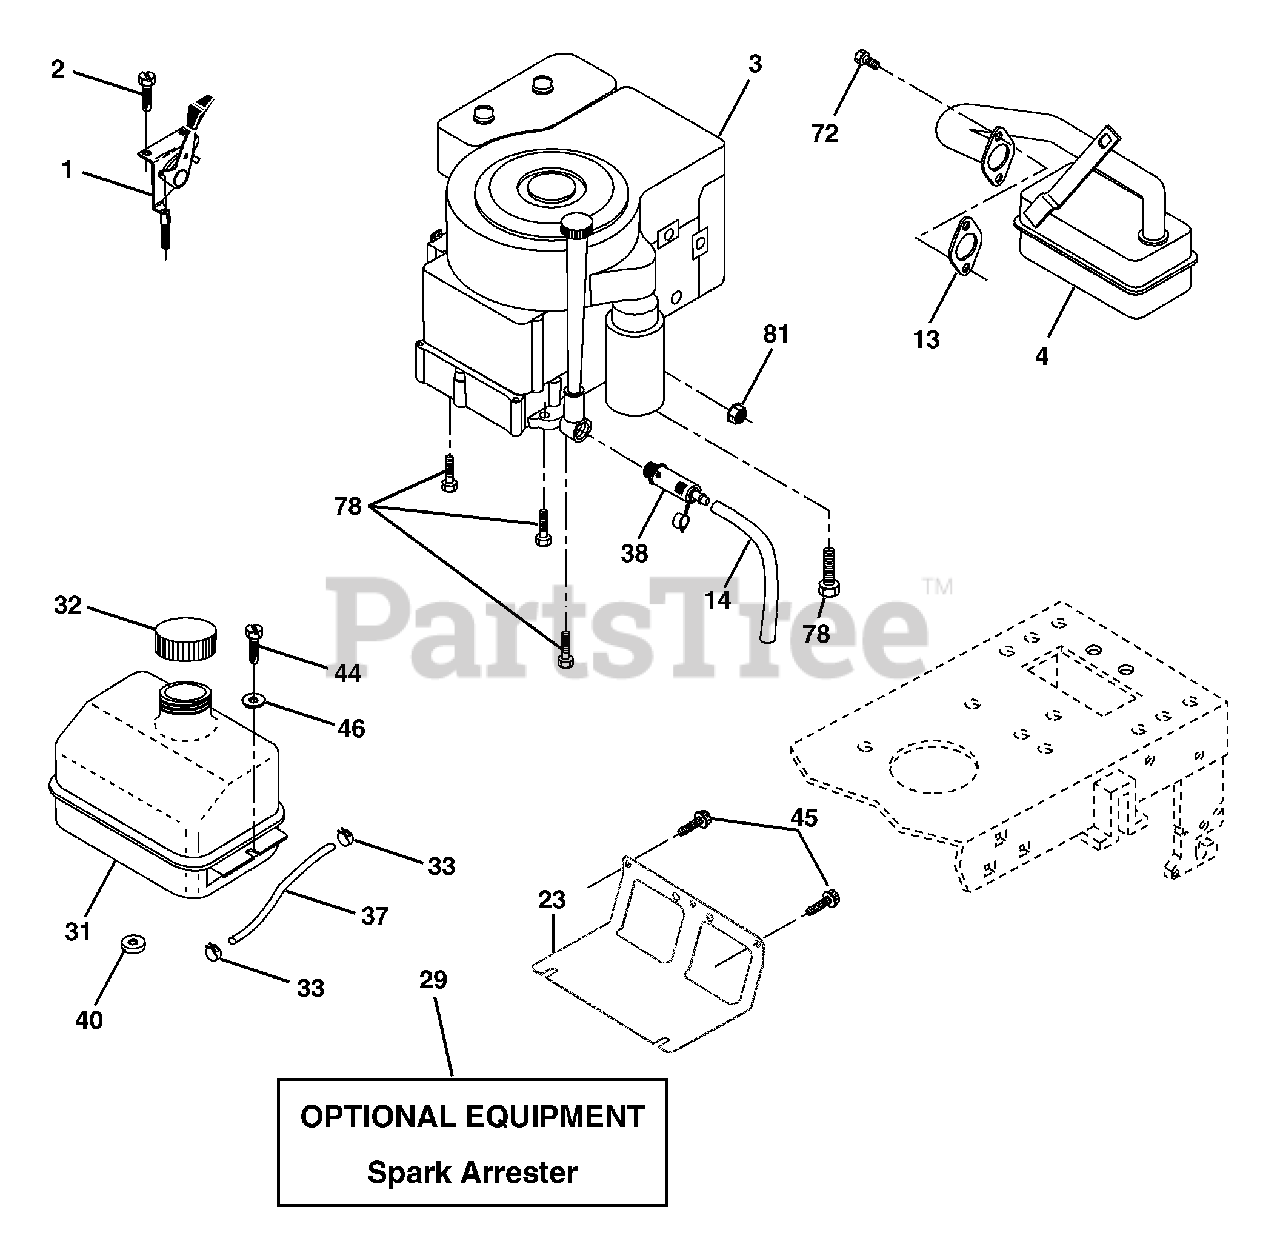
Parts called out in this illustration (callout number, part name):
1	Control Th/ch Flag
2	Screw Hex Thd Cut 1/4-20 x 1/2
13	Gasket Eng
14	Tube Drain Oil Easy
23	Shield Brn/Dbr Guard
29	Kit Spark Arrestor (Flat Scrn)
31	Tank Fuel Front
32	Cap Asm Fuel W/sym Vented
33	Clamp Hose Black
37	Line Fuel 20"
38	Plug Drain Oil Easy
40	Bushing Snap Nyl Blk Fuel Line
44	Screw Hexwsh Thdrol 1/4-20 x 3/4
45	Screw Hexwsh Thdr 3/8-16 x 3/4
46	Washer 9/32 x 7/8 x 16 Ga.
72	Screw Socket Head 5/16-18 x 1
78	Screw 3/8-16 x 1-1/4 SMGML
81	Nut Keps Hex 1/4-20 unc
